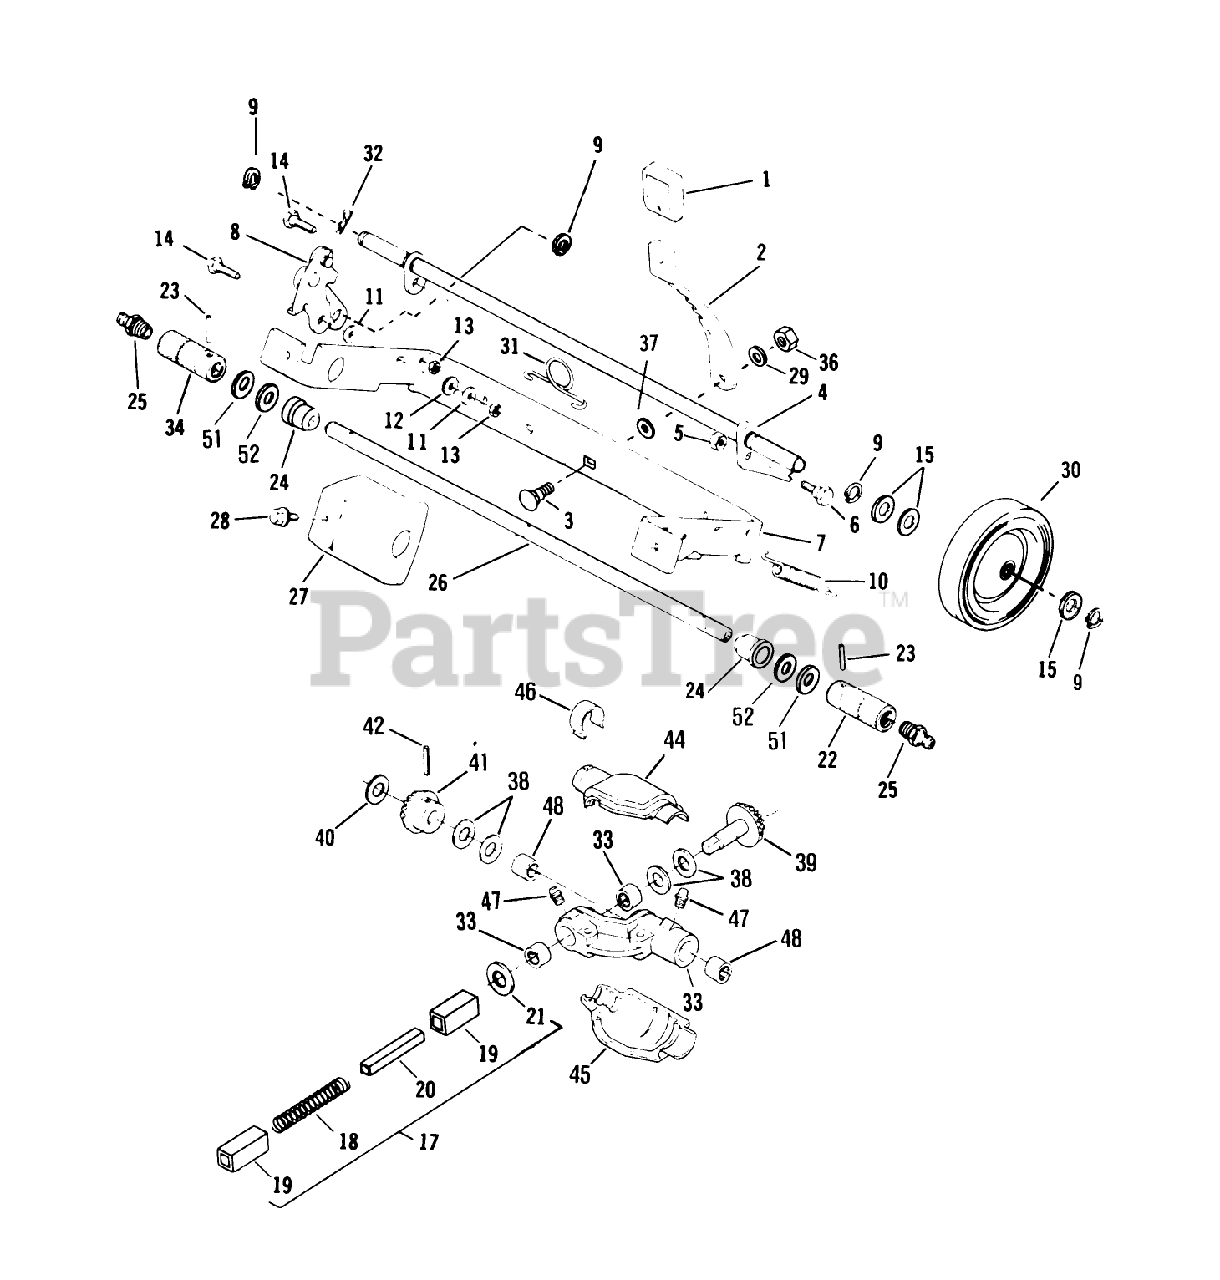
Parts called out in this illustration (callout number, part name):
2	LEVER
4	AXLE & TORQUE LUG ASM
5	LOCKNUT E
6	BOLT RB&W
7	BRACKET *GREEN
8	CLUTCH AY ARGO
9	RET RING
10	SPRING
11	WASHER S
13	STOP NUT
14	BOLT RB&W
15	SPACER
16	THRUST WASHER
18	SPRING
19	BUSHING BKWY
21	WASHER
22	ROLLER-LEFT
24	SLEEVE &BEARING AY
25	GREASE FITTING AP
26	DRIVE SHAFT & TAG
29	WASHER S
31	SPRING N.A.S
36	LOCKNUT E
37	WASHER SPRING LAR
38	THRUST WASHER
39	GEAR BEST
40	WASHER
41	GEAR ADVANCE
42	ROLL PIN
44	GEAR COVER UPPER
47	**FITTING LINCOLN
